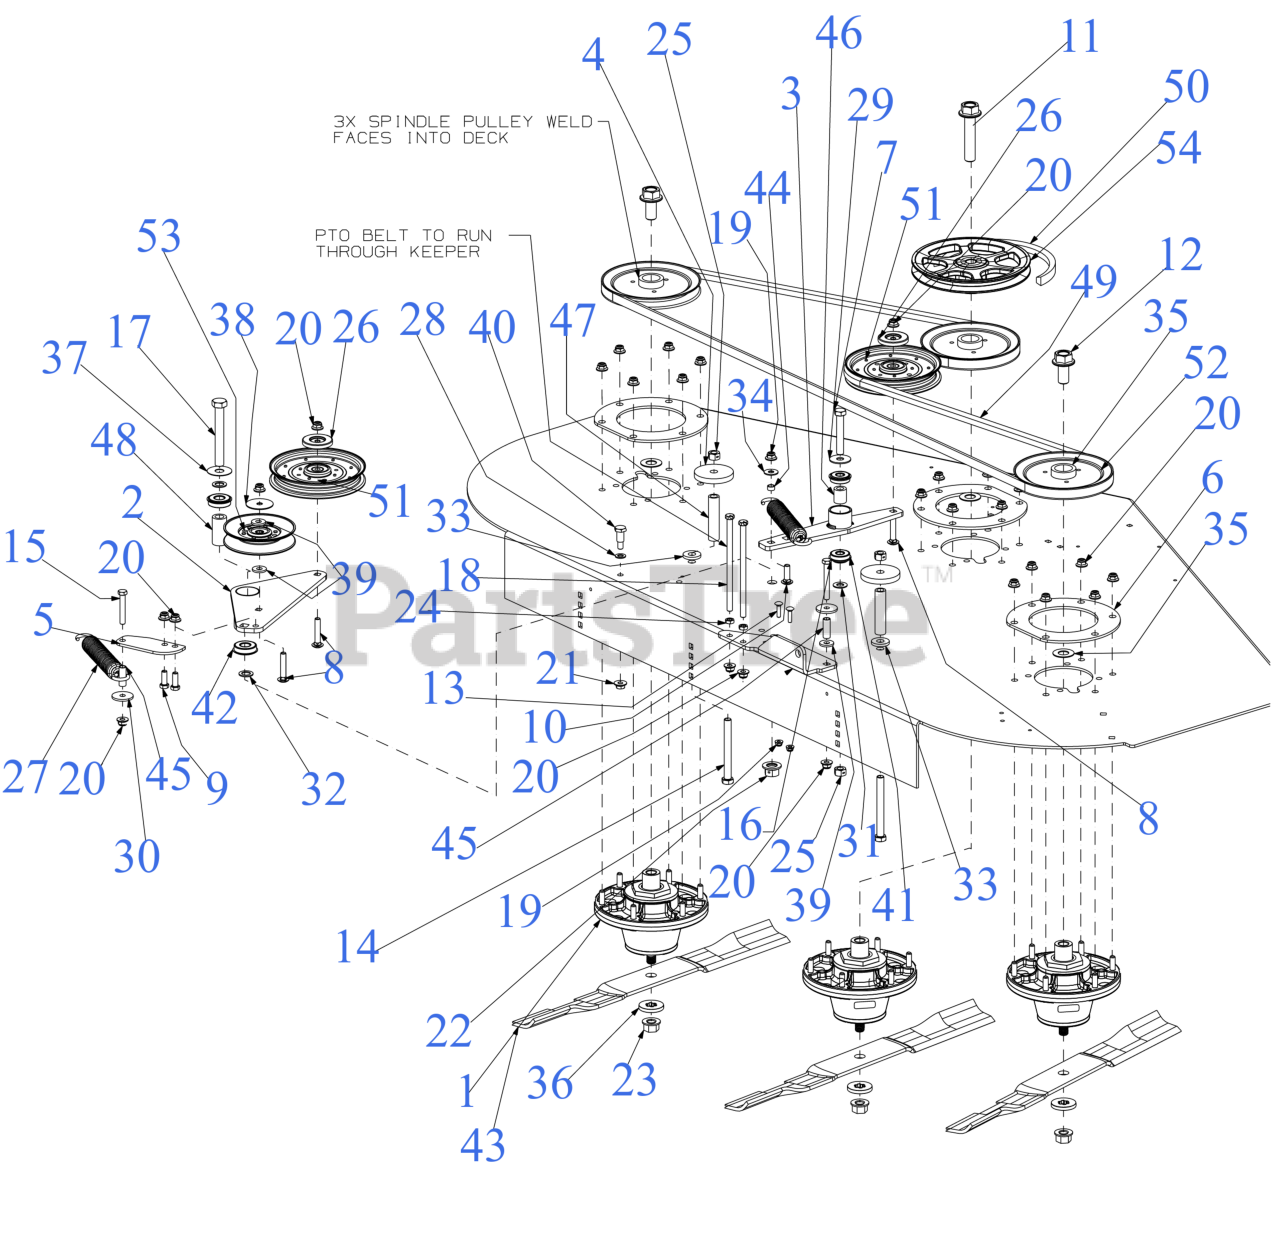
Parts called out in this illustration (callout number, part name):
1	SPINDLE ASSEMBLY
3	IDLER BRACKET
4	SPACER PLATE
6	SPINDLE SUPPORT BRACKET TOP/BTM
7	SCREW-HEX 1/2-13 x 3.00
8	CARRIAGE BOLT 3/8-16 x 2
9	SCREW 3/8-16 x 1 GR5
10	CARRIAGE BOLT 3/8-16 X1.25 GR5
11	CAP SCREW-HHFLG 3/4-10 X 3.50 GR8
12	CAP SCREW-HHFLG 3/4-10 X 1.50 GR8
13	SCREW 1/4-20 x 1 GR5
14	SCREW 1/2-13 x 4.5 GR 5
15	SCREW 3/8-16 x 2.25 GR5
16	SCREW 3/8-16 x 2.75 GR5
17	SCREW 5/8-18X4.5 GR5
18	SCREW 3/8-16 x 7.00 GR5
19	FLANGE LOCK NUT
21	FLANGE LOCK NUT
23	FLANGE NUT - 5/8-18 GDE 8
24	HEX JAM NUT 3/8-16 GR5
25	HEX NUT CTR LK 1/2-13
26	PULLEY CAP
27	SPRING 1.25" DIA x 8.5" LONG
28	FLAT WASHER
29	WASHER .51 x 1.5 x .07
30	FLAT WASHER .406X1.500X.105
31	FLAT WASHER .510 x .995
32	FLAT WASHER
33	FLAT WASHER .531 x 1.25 x .181
34	WASHER-.395 x 1.0 x .62
35	FLAT WASHER
36	FLAT WASHER - SPECIAL
37	FLAT WASHER-.63IDX1.595ODX.62
38	HUB CAP WASHER .406 x 1.92 x .060
39	FLAT WASHER .406ID X1.0 OD
40	SHOULDER SCREW .500
41	ROLLER BEARING .5X1.37X.44
42	BALL BEARING W/RET
43	25" HI-LIFT BLADE
46	SPACER 0.51 x 0.88 x 1.00
48	SPACER 0.63 x 1.00 x 2.01
50	V-BELT B-SEC x 113.4"
51	IDLER PULLEY
52	SPINDLE PULLEY 7"
53	IDLER PULLEY 5.06 OD
54	SPINDLE DRIVE PULLEY 8.347 DIA
